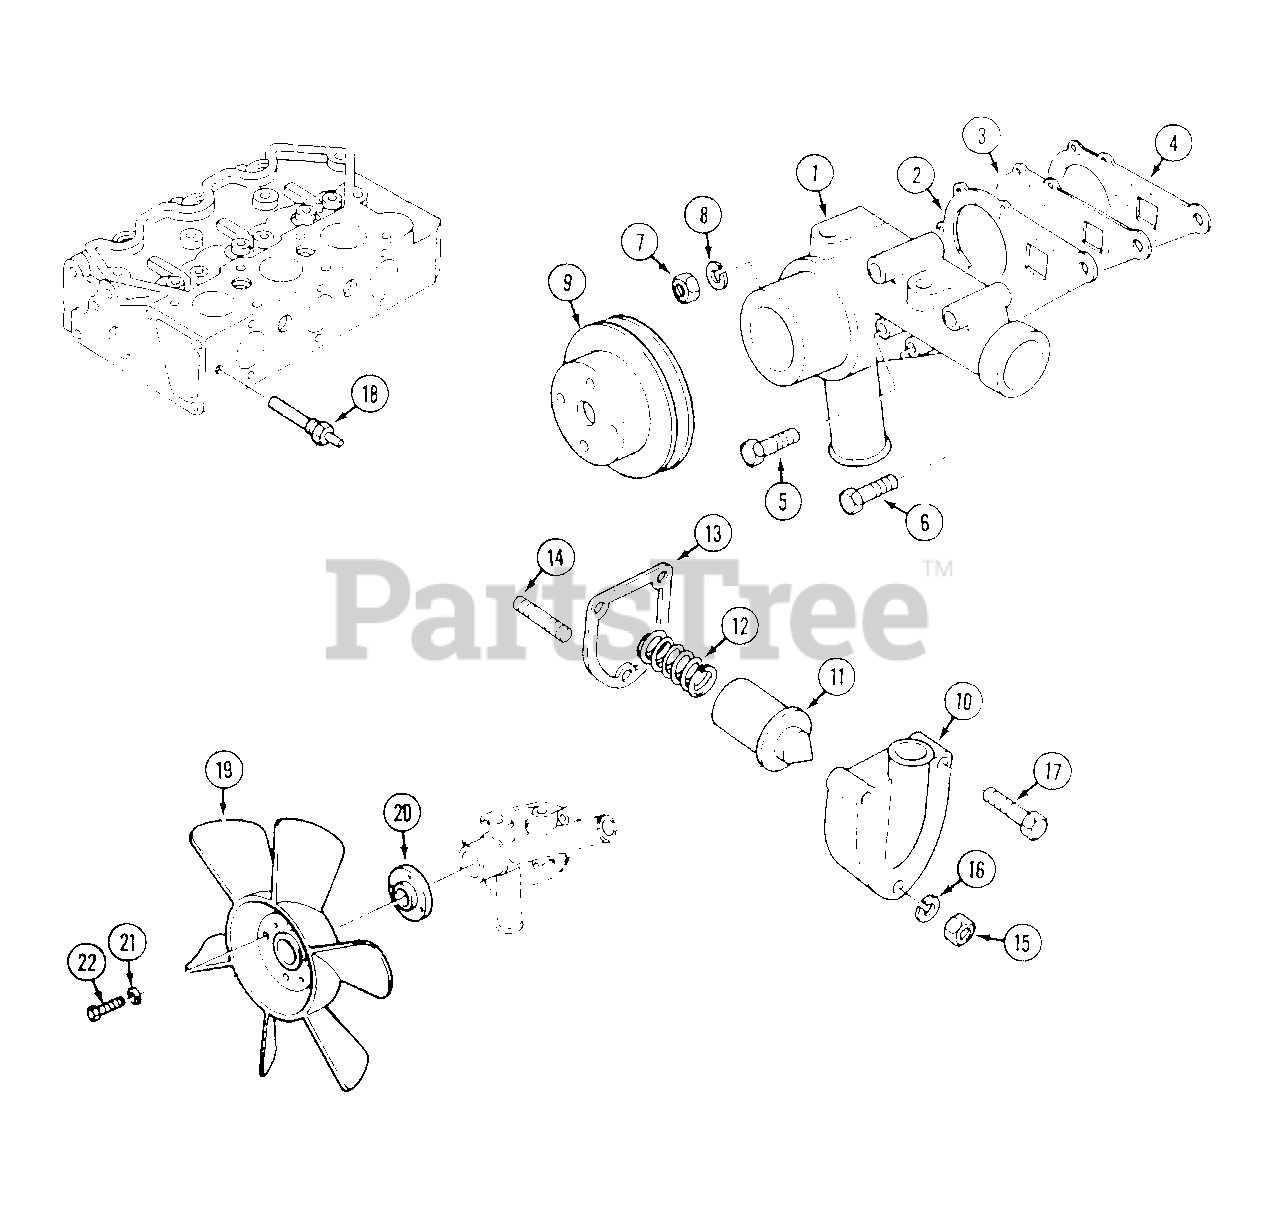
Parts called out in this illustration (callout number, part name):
1	PUMP - water
3	BACKPLATE
5	SCREW
6	SCREW
7	NUT
8	WASHER
9	PULLEY
10	HOUSING
12	SPRING
14	STUD
15	NUT
16	WASHER
17	SCREW
18	SENDER - temperature
20	SPACER - fan
21	LOCKWASHER - 1/4"
22	SCREW - M6 - 1.0 x 45
